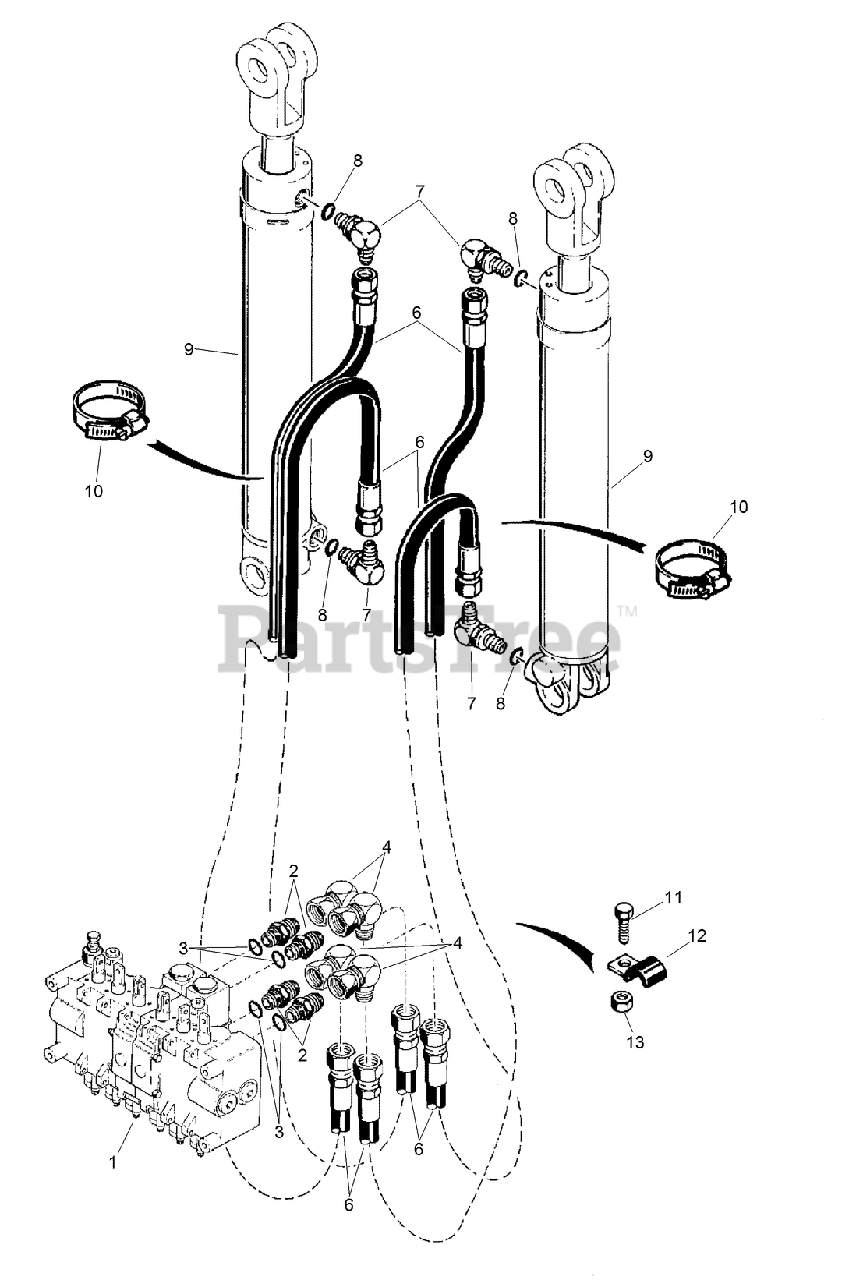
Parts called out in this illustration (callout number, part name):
1	HYD CONTROL VALVE ASM
2	CONNECTOR
3	O-RING
4	ELBOW-SWIVEL, 90 DEG
7	ELBOW-90 Adj 37FL, 3/8 x 1/2 Tube
8	O-RING
9	HYD CYLINDER ASM
10	CLAMP-Hose #56
11	BOLT-Hex, 5/16 NC x 1-1/2 inch
12	CLAMP-TUBE
13	NUT-Hex Serrated Flange, 5/16 inch NC
